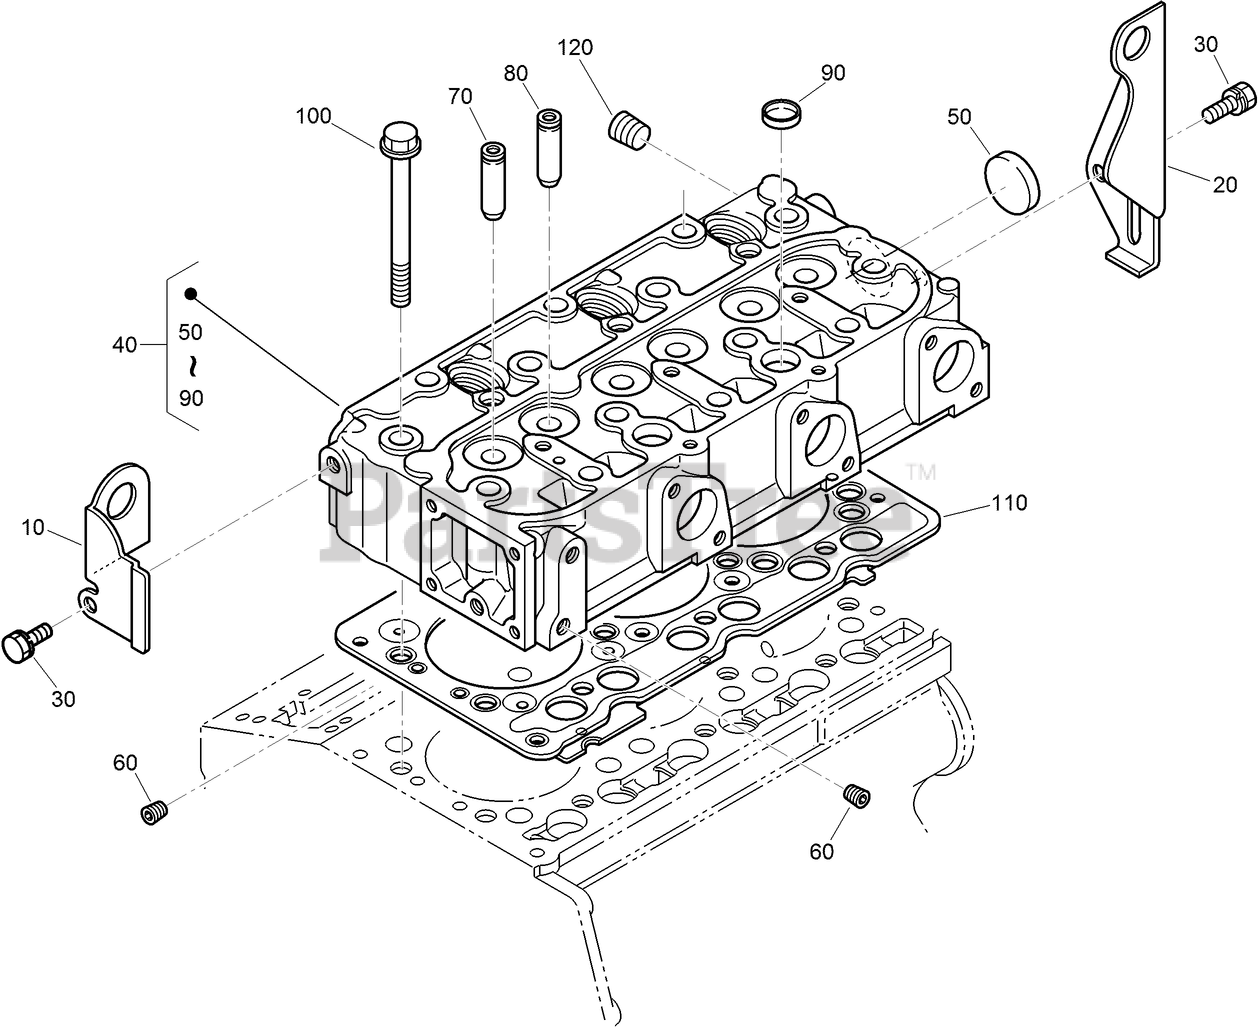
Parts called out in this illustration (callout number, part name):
10	HOOK-ENGINE
20	HOOK-ENGINE
40	CYLINDER HEAD ASM
50	CAP-SEALING
70	GUIDE-VALVE, INLET
80	GUIDE-VALVE, EXHAUST
90	CAP-SEALING
100	BOLT-HEAD, CYLINDER
110	GASKET-HEAD, CYLINDER
